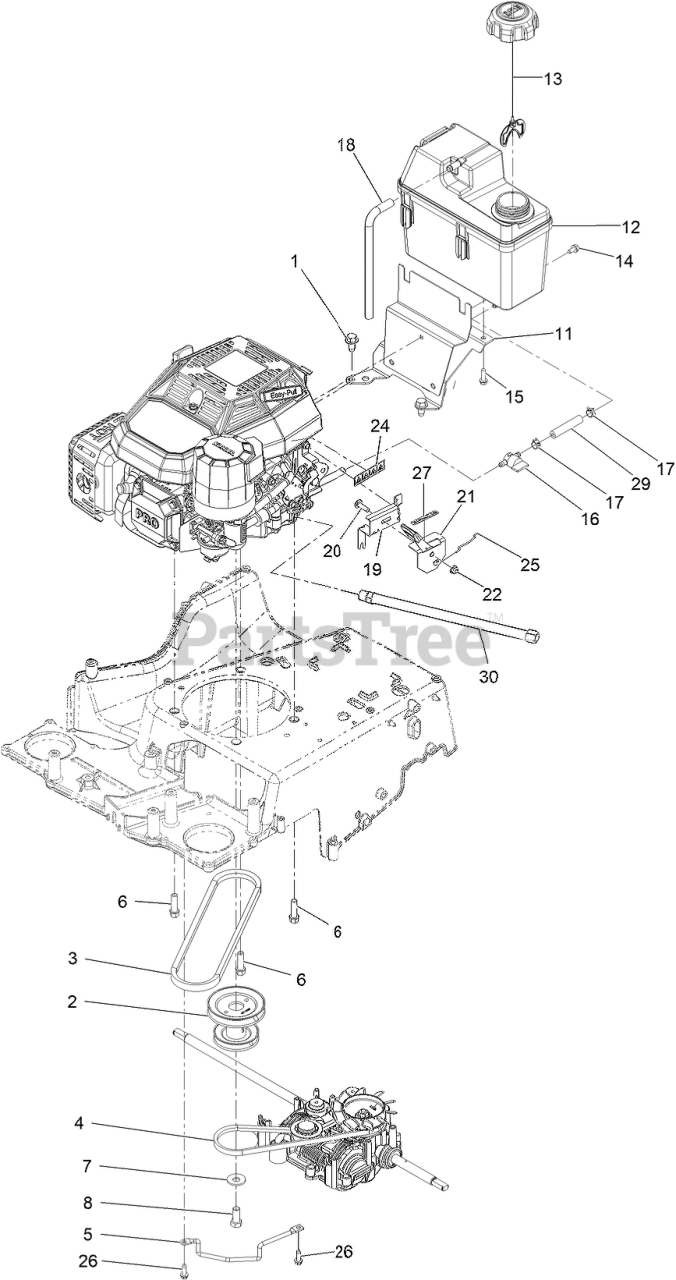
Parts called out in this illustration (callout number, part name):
1	SCREW-HWH
2	Pulley-Engine
5	ROD-GUIDE, BELT
6	SCREW-TAPTITE
7	WASHER-BELLEVILLE
8	SCREW-HH
11	TANK MOUNT ASM
12	TANK-FUEL
13	CAP-FUEL
14	SCREW-HWH
15	SCREW-HWH
16	VALVE-FUEL
17	CLAMP-HOSE
18	HOSE-VENT, CANISTER
19	BRACKET-THROTTLE
20	SCREW-CARR
21	CONTROL-THROTTLE
24	DECAL-WARNING, ENGINE
25	Wire-Link
26	SCREW-HWHTF
27	DECAL-THROTTLE, CHOKE
29	HOSE-FUEL
30	HOSE-DRAIN, OIL
